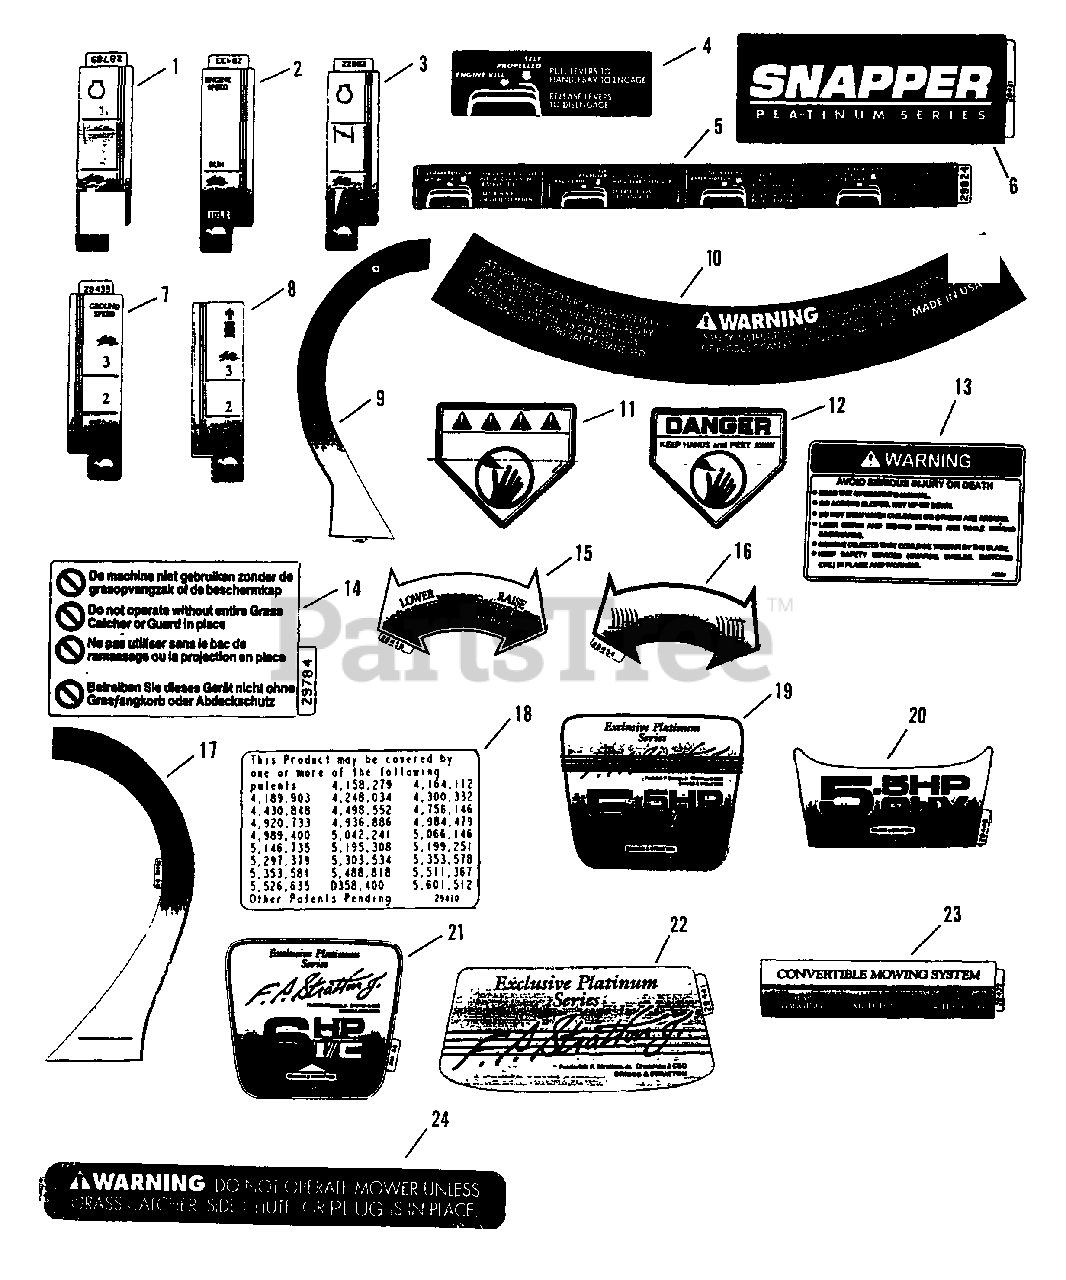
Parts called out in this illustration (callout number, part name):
1	DECAL, Engine Speed (Without Choke)
2	DECAL, Engine Speed (Without Choke)
3	DECAL, Engine Speed (With Choke)
4	DECAL, OPC/SP Instruction
5	DECAL, OPC/SP Instruction
6	DECAL, Console
7	DECAL, 3-Speed Control
8	DECAL, 3-Speed Control
9	DECAL, Cover
10	DECAL - WARNING (Deck)
11	DECAL - WARNING (Deck)
12	DECAL - DANGER
13	DECAL, Warning
14	DECAL - DANGER
15	DECAL, Height Adjustment
16	DECAL, Height Adjustment
17	DECAL, Deck (Right Side)
18	DECAL, Patent Numbers
19	DECAL, Briggs & Stratton, 5.5HP Diamond-Plus I/C
20	DECAL, Briggs & Stratton, 5.5HP Diamond-Plus I/C OHV
21	DECAL, Briggs & Stratton, 6HP Diamond-Plus I/C
22	DECAL, "Exclusive Platinum Series"
23	DECAL, Convertible Mower
24	DECAL, - WARNING
